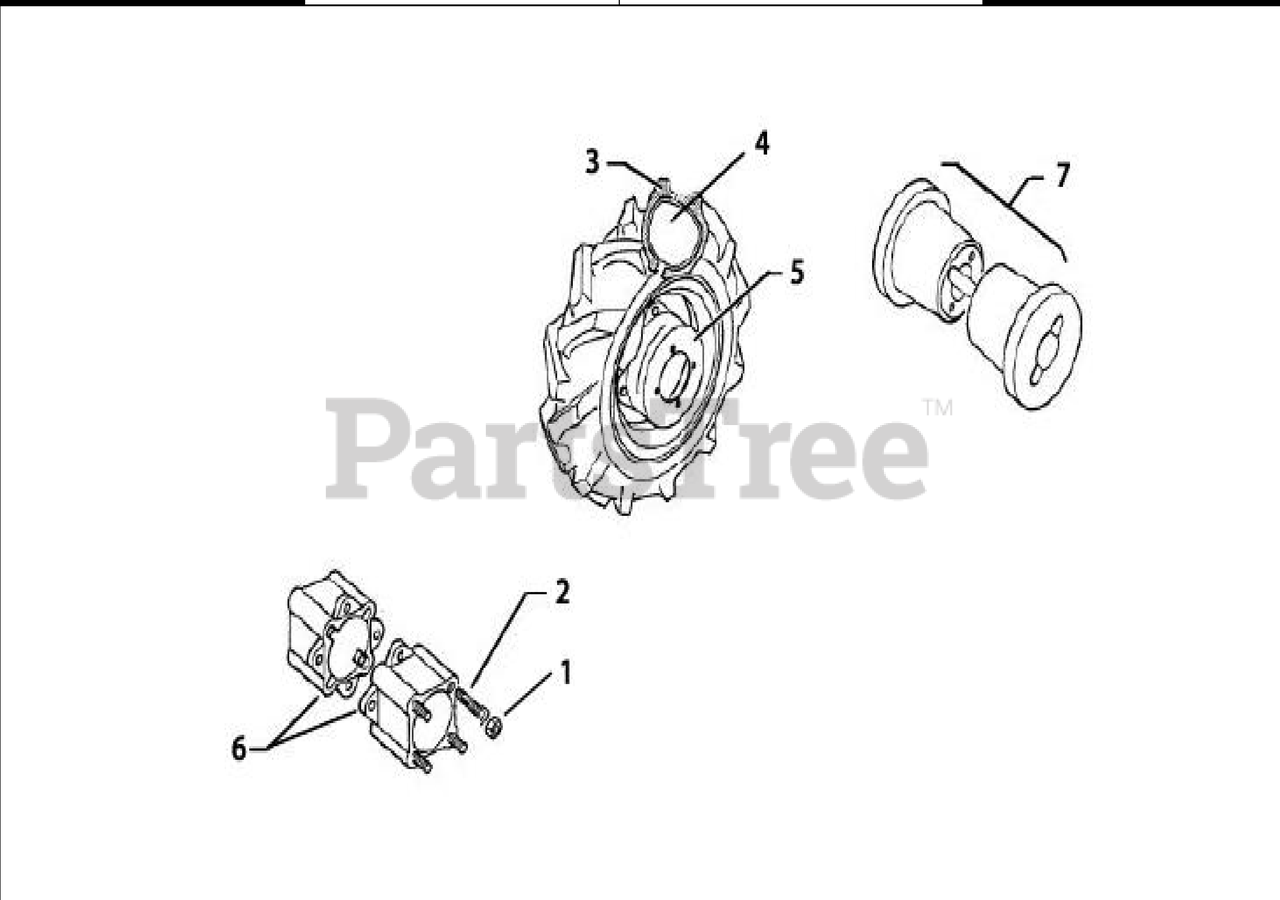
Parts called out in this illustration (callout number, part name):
1	NUT M10 NYLOCK
2	STUD M10X46X24X16
3	TIRE 5.00X12”
3	WHEELS AVAILABLE
3	WHEEL 4.00 X10 / 5.00 X10”
4	INNER TUBE 5.00X12”
4	TIRE 5.00 X 10”
4	TIRE 6.50X12”
5	WHEEL 5.00X12
5	INNER TUBE 5.00 X10”
5	INNER TUBE 6.50X12”
6	WHEEL EXTENSION KIT
7	WHEEL WEIGHTS 66 lbs (10” Wheels)
7	WHEEL WEIGHTS 150 lbs (12” Wheels)
